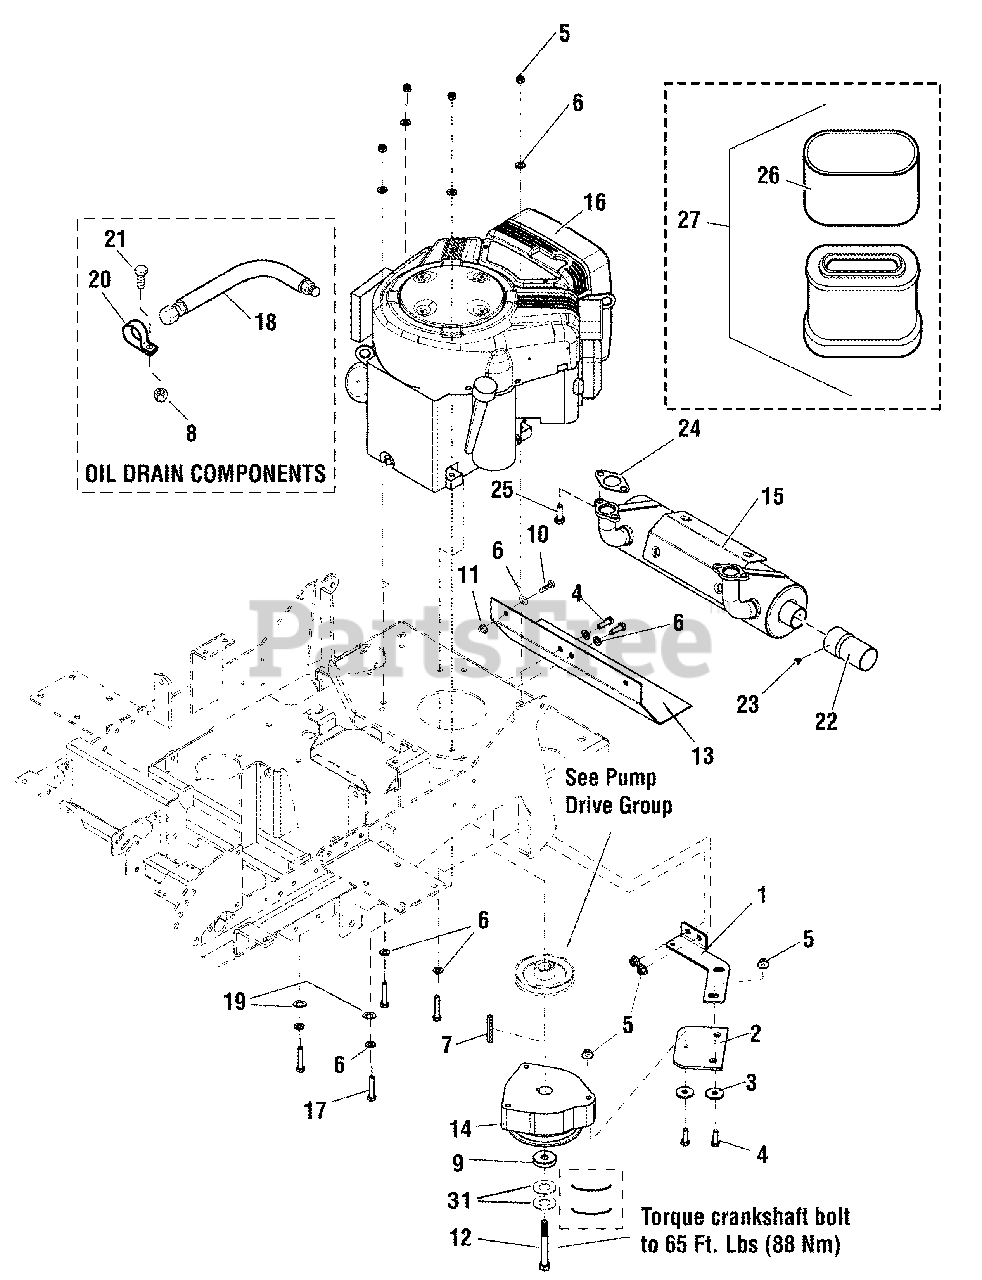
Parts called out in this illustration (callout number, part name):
1	PLATE, CLUTCH ANCHOR
2	CLUTCH ANCHOR PAD
3	WASHER, .34 X 1.25 X 10 GA
4	BOLT, 5/16-18 X 1" GD5 YZ
5	NUT, 5/16-18 HEX NYLOCK FLANGE
6	WASHER, 5/16" SAE
7	KEY, 1/4" SQ. X 2 1/4
8	NUT, 1/4-20 HEX SERR. FLANGE
9	SPACER, .45 X 1.88 X .38
10	BOLT, 5/16-18 X 3/4" GRD5
11	NUT, 5/16-18 HEX LG SERR FLG.
12	BOLT, CRANKSHAFT, 7/16-20 X 3-1/4"
13	PLATE, HEAT SHIELD - ORG
14	* CLUTCH, # 51110100,ELECTRIC, 1" SHAFT
15	MUFFLER, B&S-ELS
15	MUFFLER, B&S, ELS & COMM TURF
16	ENGINE, BRIGGS & STRATTON
17	BOLT, 5/16-18 X 2-1/4" GD5 YZ
18	HOSE, OIL DRAIN
19	WASHER, 5/16" INT. TOOTH LOCK
20	CLAMP, VINYL INSULATED
21	BOLT, 1/4-20 X 3/4" GD5 YZ
22	EXTENSION, TAILPIPE, 3" - BLK
24	GASKET, EXHAUST
25	SCREW, SEM HEX HEAD
26	PRE CLEANER (SV)
27	AIR CLEANER W/ PRE CLEANER (SV)
31	BELLEVILLE WASHER 1.1875 X .442 X .089
